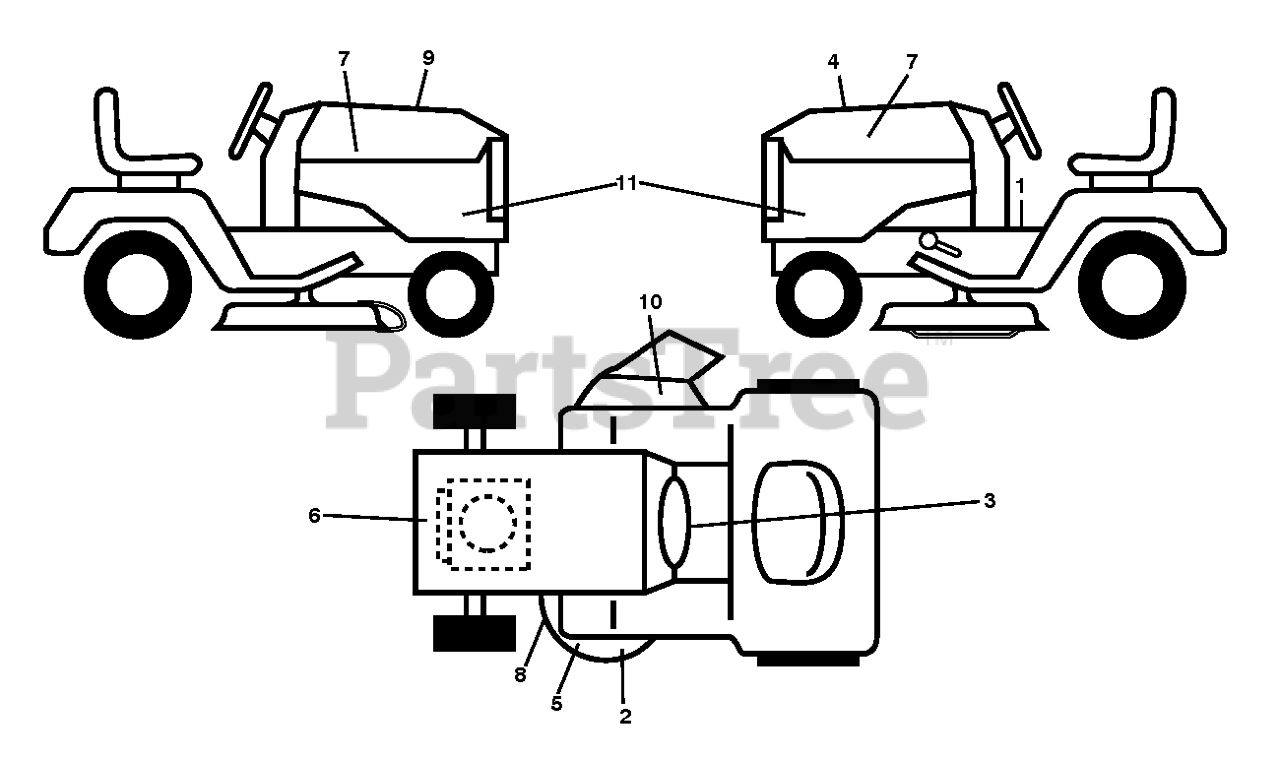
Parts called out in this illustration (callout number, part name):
1	DECAL.FENDER.WARNING.ENGLISH
2	DECAL.WB.178MM.15.HUSQ.NEWBRAN
3	DECALS.WARN.CA.SPKARREST/PROP
4	DECAL.RPL.BSM44.INTK.TLW
5	DECAL.MOWER.CAUTION.TENSION.AR
6	DECAL.ENG.BS.INTK.24HP.382016
7	DECAL.WB.178MM.15.HUSQ.NEWBRAN
8	DECAL.MOWER.SCH.48/54.PREM
9	DECAL.WARNING.CUST.RESP.E85.
10	DECAL, DECK DEFLECTOR, WARNING
11	DECAL SIDE PANEL
